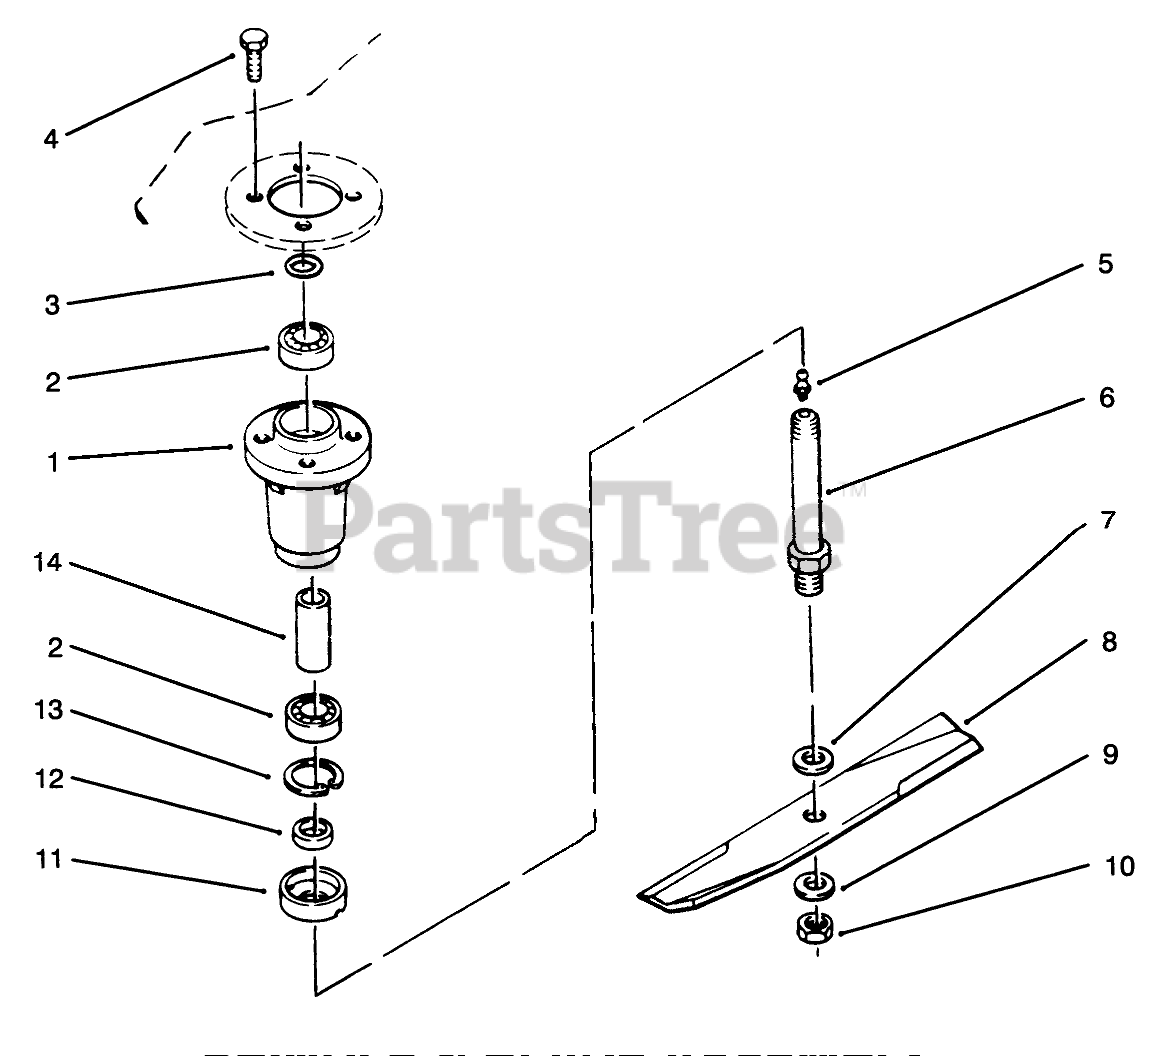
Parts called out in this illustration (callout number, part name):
1	HOUSING-SPINDLE
2	BEARING-BALL
3	O RING
4	SCREW-HH
5	FITTING-GREASE
6	SHAFT-SPINDLE
7	WASHER-FLAT
8	Blade
9	WASHER-FLAT
10	NUT-JAM
11	CUP-SPINDLE
12	SPACER-BLADE
13	RING-RETAINING
